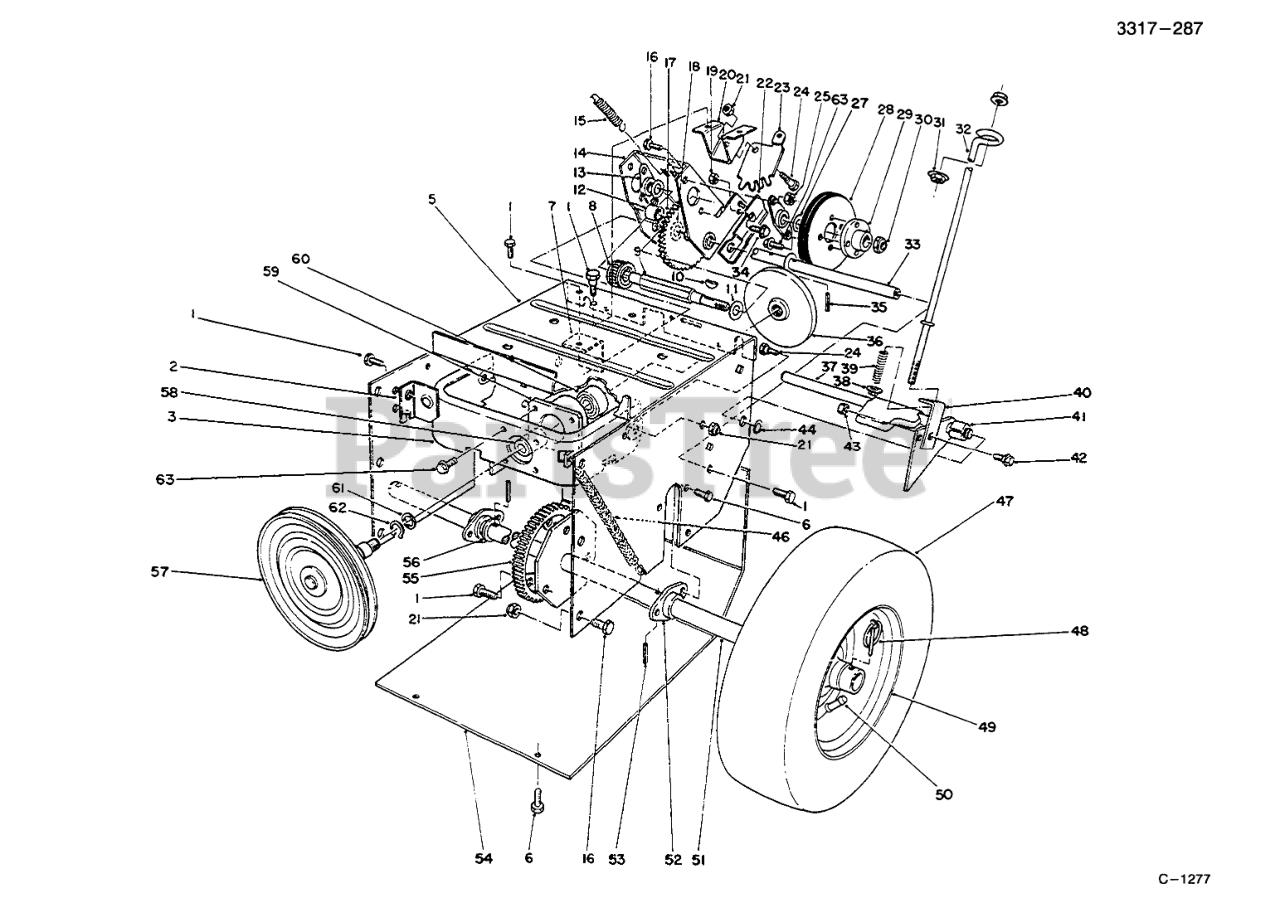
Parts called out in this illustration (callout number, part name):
1	SCREW-HWHTF
2	BRACKET-MOUNT, FRONT
3	Frame-Friction Plate
5	Frame-Traction
6	SCREW-HWH
7	BRACKET-MOUNT, REAR
8	PINION
9	SHAFT-WHEEL, FRICTION
10	KEY-WOODRUFF
11	WASHER-FLAT
12	5/8ID X 1LG BUSHING
13	BEARING-WHEEL, FRICTION
14	BRACKET-SLIDING
15	SPRING-TRACTION
16	SCREW-HH
17	Intermediate Gear & Bushing (Incl. Ref. #12)
18	WASHER-SPECIAL
19	NUT-LOCK, NI
20	MOUNT-LEVER
21	NUT-LOCK, NI
22	CAM-RECEIVER
23	GEAR-QUADRANT
24	BOLT-SHOULDER
25	NUT-LOCK, NI
27	WASHER-THRUST
28	WHEEL-FRICTION
29	HUB-WHEEL, FRICTION
30	NUT-LOCK, NI
31	NUT-HF
32	ROD-TRACTION, LOWER
33	SHAFT-PIVOT
34	SCREW-HH
35	PIN-SPRING
36	PLATE-FRICTION
37	Traction Engagement Asm.
38	NUT-HHF
39	SPRING
40	BRACKET-TRACTION
41	SPACER
42	SCREW
43	NUT-LOCK, NI
44	RING-RETAINING
46	SPRING-PLATE, FRICTION
48	PIN-LYNCH
49	RIM-WHEEL
50	TUBE-INNER
51	SHAFT-AXLE
52	BEARING-AXLE
53	PIN-SPRING
54	Bottom Cover
55	GEAR-AXLE
56	WASHER-THRUST
57	PULLEY AND DRIVE ASM
58	BUSHING
59	HUB-FRAME, TRACTION
60	BEARING-BALL
61	WASHER-THRUST
62	RING-RETAINING, EXT
63	SCREW
